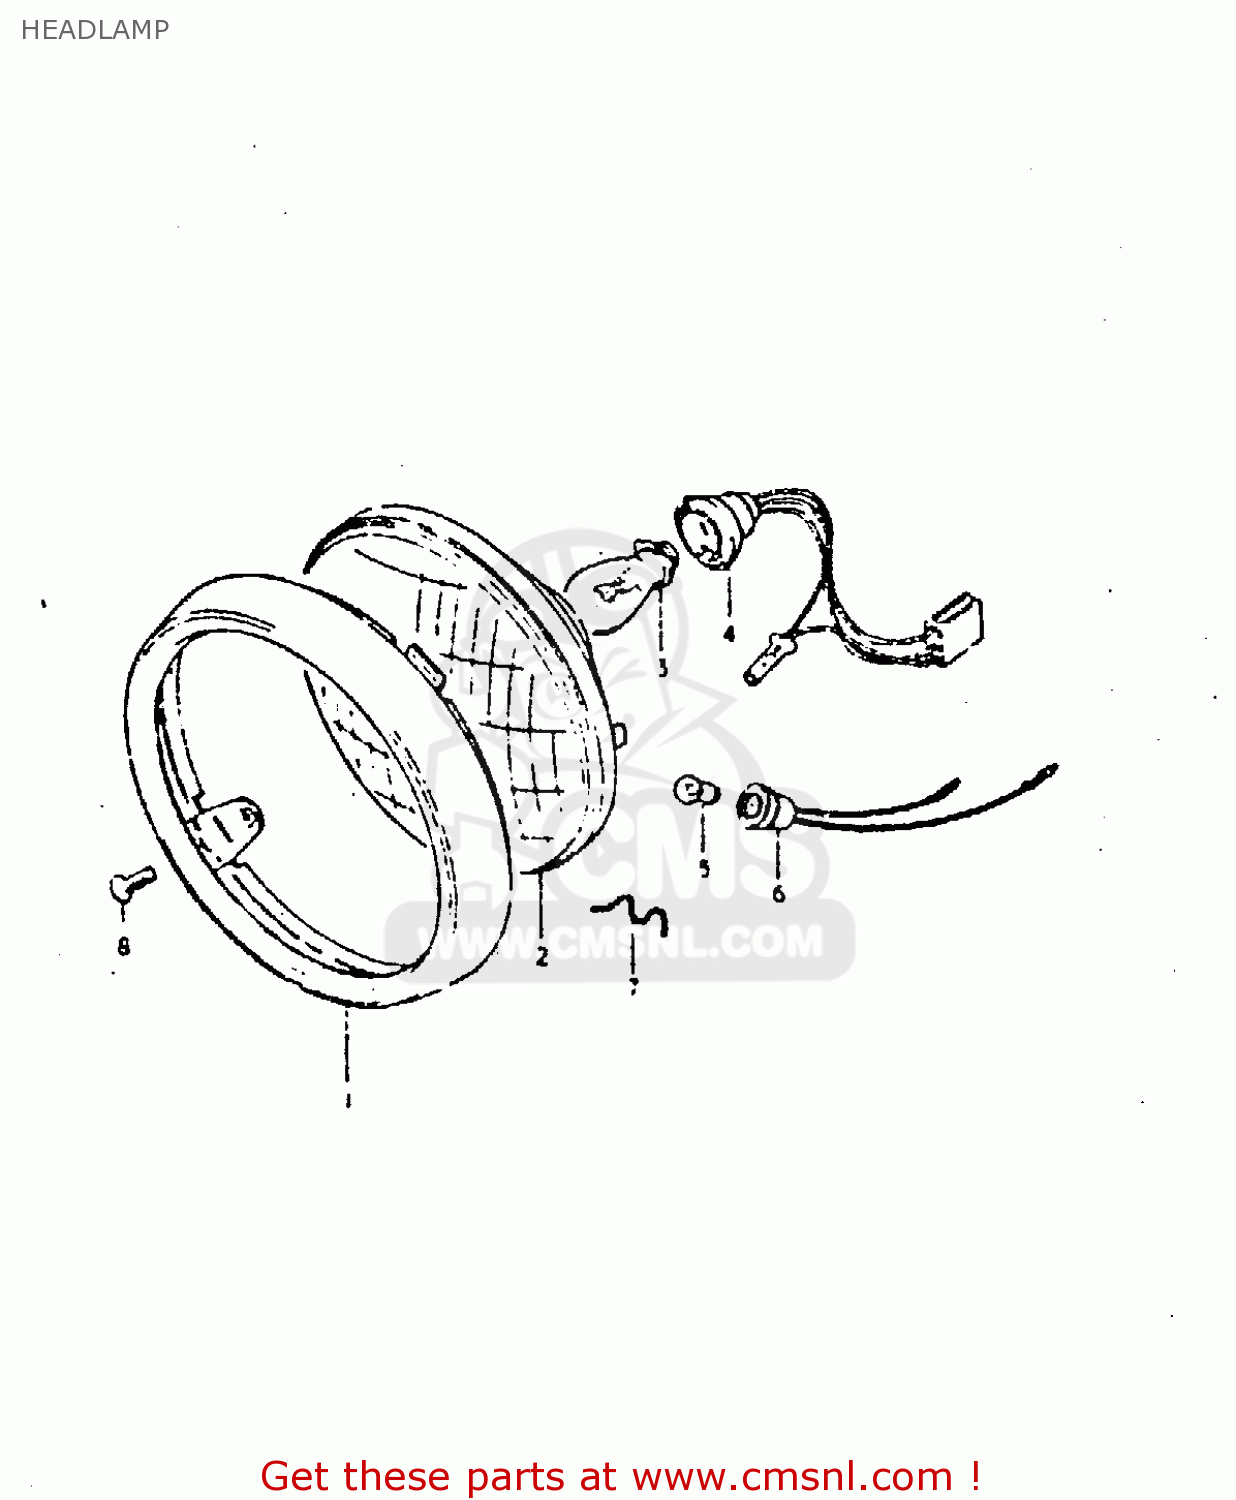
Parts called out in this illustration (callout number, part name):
1	RIM
2	LAMP UNIT
3	BULB
4	SOCKET
5	BULB(12V3.4W,STANLEY,A72A)
6	SOCKET
7	SPRING
8	SCREW
